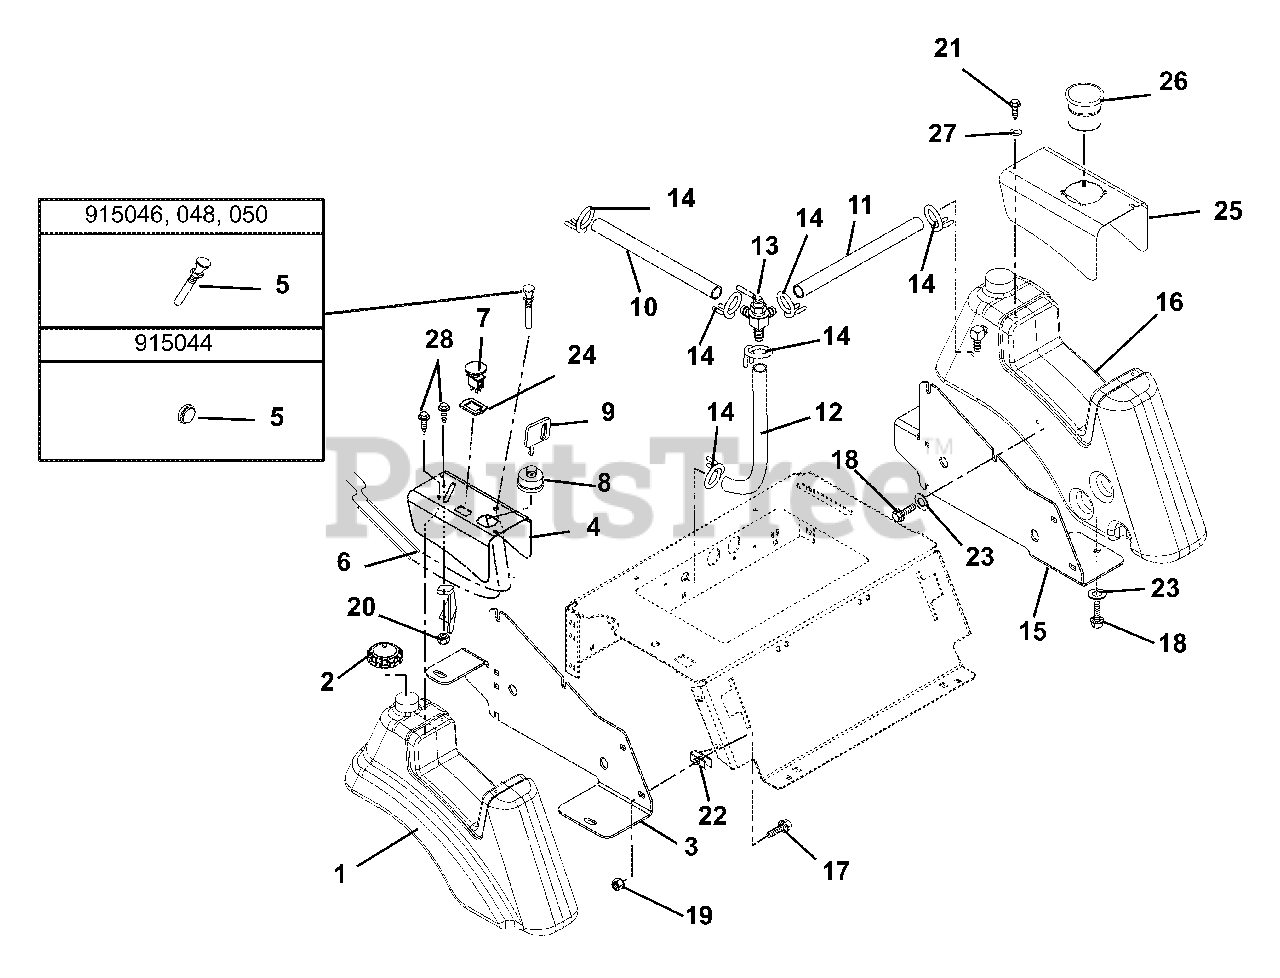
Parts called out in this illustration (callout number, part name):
1	Tank, Fuel - Right Hand
2	Fuel Cap
3	Seat Plate Right Hand
4	Right Hand Console
5	Choke Cable (046, 048, 050)
5	Hole Plug, Plastic .44 Hole (044)
6	Throttle Cable (046, 048, 050)
6	Throttle Cable (044)
7	Switch, Clutch
8	Key Switch
9	Key with Cap
10	Gas Line, Bulk .25 I.D. x 38 Long
11	Gas Line, Bulk .25 I.D. x 27 Long
12	Gas Line, Bulk .25 I.D. x 17 Long (046, 048, 050)
12	Gas Line, Bulk .25 I.D. x 14 Long (044)
13	Valve, Fuel
14	Clamp, Hose Wire .490/.510 x .116
15	Seat Plate Left Hand
16	Tank, Fuel - Left Hand
17	Bolt, Round Head Square Neck .38-16 x 1.00 Grade 5
18	Bolt, Serrated Hex Flange Washer Head .312-18 x .75
19	Nut .38-16 Flange Nyloc
20	Nut-Locking-Nylon 10-24 with Insert
21	Screw,Machine 10-24 x 3/8 Slotted Hex
22	Retainer .38 Push-On
23	Washer, Flat Steel .328 x 1.00 x .094
24	Shim, PTO Switch
25	Console, Left Hand
26	Cup Holder
27	Washer, Fender 3/16 x 3/4
28	Screw-Machine 10-24 x .50 Hex Washer Head
